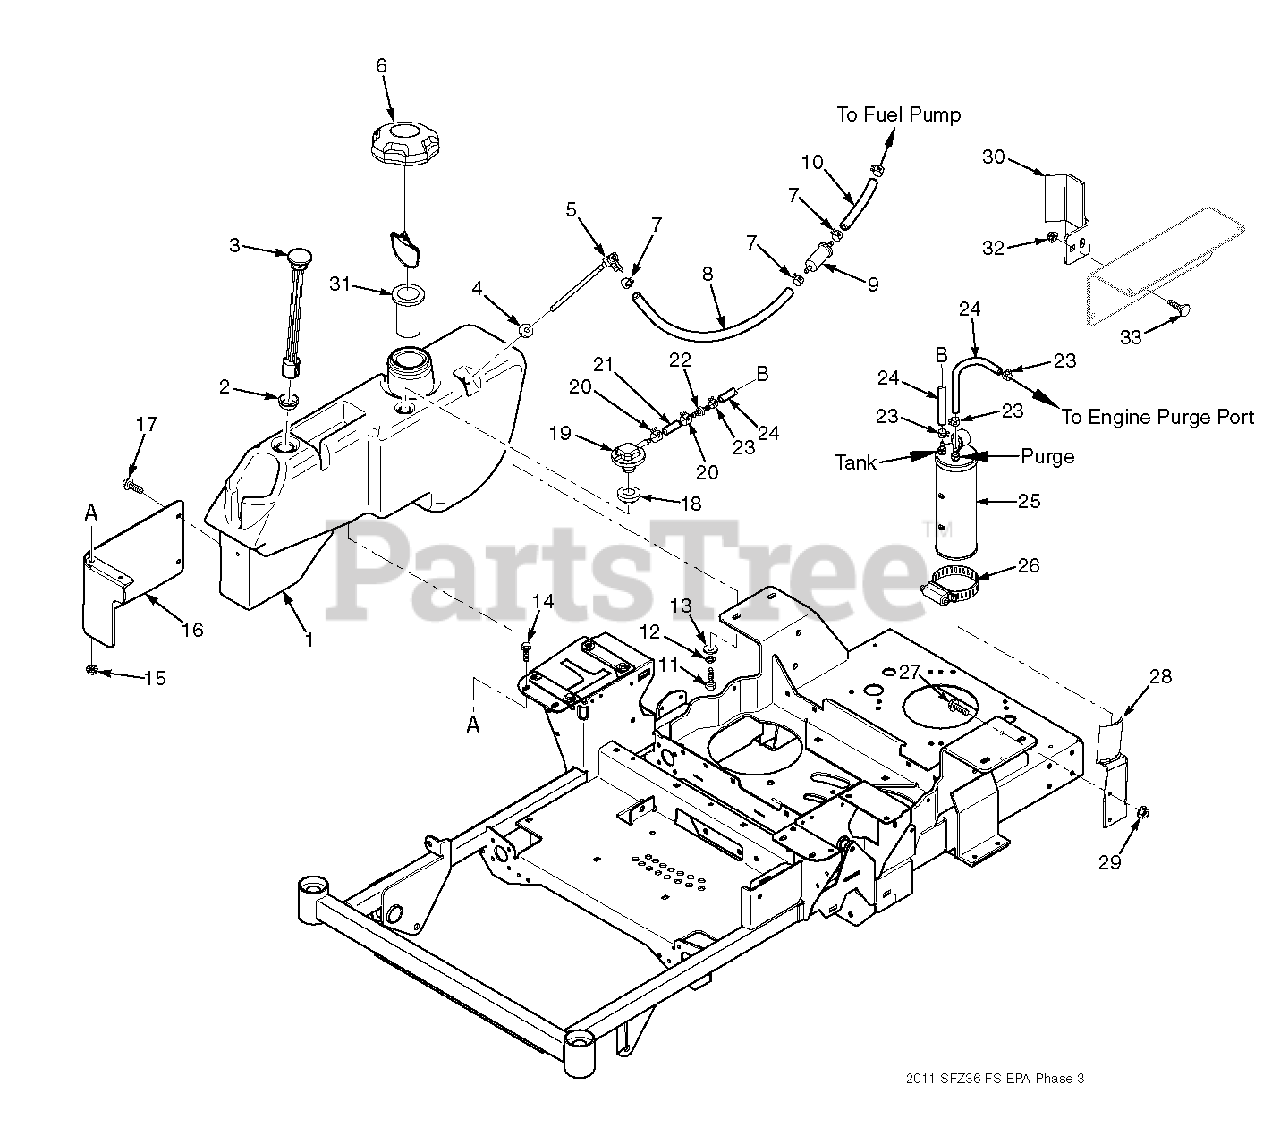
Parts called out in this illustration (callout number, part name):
1	Fuel Tanks Assembly
2	Grommet
3	Fuel Gauge Assembly
4	Bushing, 0.56 Dia. Viton
5	Fuel Tube Assembly
6	Fuel Cap, Tethered
7	Clamp, Fuel Hose 1/4" ID
8	Fuel Hose, 1/4" ID Non-Perm
9	Fuel Filter
10	Fuel Hose
11	Bolt, Hex Head 5/16-18 x 3/4"
12	Lockwasher, 5/16- Spring
13	Flatwasher, 5/16-.375 x .875 x .083
14	Bolt, Hex Head 1/4-20 x 3/4" Serrated Flange
15	Nut, Serrated Flange 1/4-20
16	Control Cover, RH
17	Bolt, Hex Head 1/4-20 x 1/2" Serrated Flange
18	Grommet, Viton
19	Remote Vent
20	Clamp, Fuel Hose 7/32 ID
21	Hose, 1/4" Vapor Recovery
22	Mender, 1/4 x 3/16 w/0.02 Hole
23	Clamp, Vapor Recovery Hose 3/16"
24	Hose, 3/16"
25	Carbon Canister
26	Clamp, Hose
27	Bolt, Hex Head 1/4-20 x 3/4"
28	Bracket Weldment
29	Nut, Serrated Flange 1/4-20
30	Guard Weldment, Canister
31	Tube, Fuel Tank Insert
32	Nut, 5/16-18 Serrated Flange
33	Bolt, Carriage 5/16-18 x 1/2"
